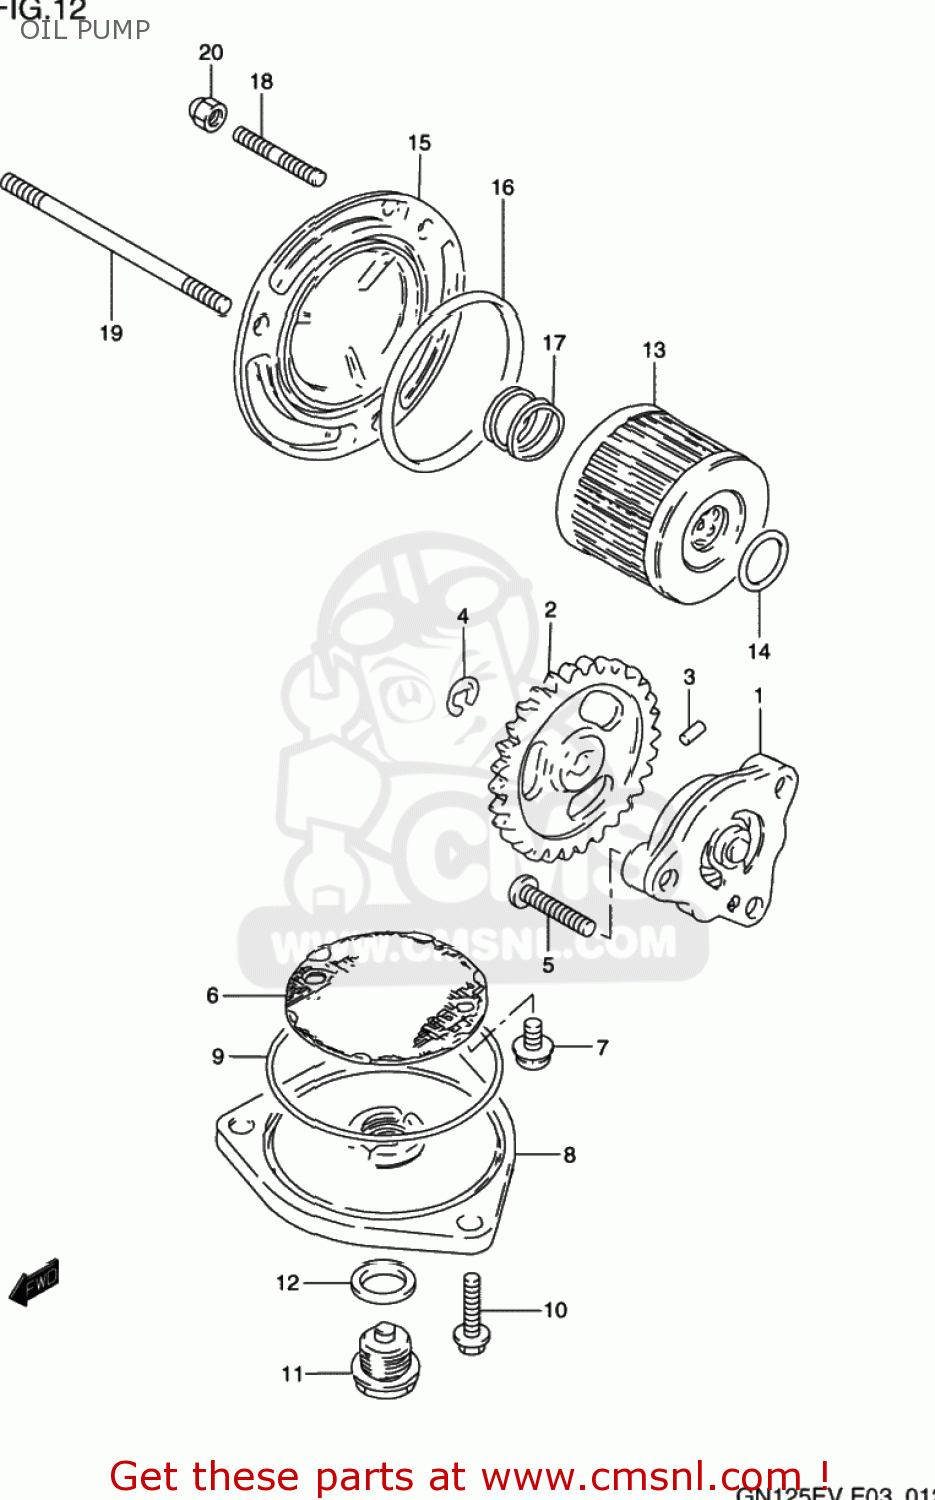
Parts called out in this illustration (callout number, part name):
1	PUMP ASSY,ENGINE OIL
2	GEAR,ENG OIL PUMP DRIVEN(NT:30
3	PIN(2.5X11.8)
4	E.RING
5	SCREW
6	STRAINER,ENGINE OIL
7	SCREW
8	CAP,OIL STRAINER
9	O RING(D:2.4,ID:60.5)
10	SCREW
11	PLUG(14X12)
12	GASKET(13.8X18.8X4.8) (NAS)
13	FILTER ASSY,ENGINE OIL
14	O RING(D:1.9,ID:13)
15	CAP,OIL FILTER
16	O RING(D:2.4,ID:52.6)
17	SPRING
18	STUD 6X12
19	STUD BOLT, 6X8
20	NUT
